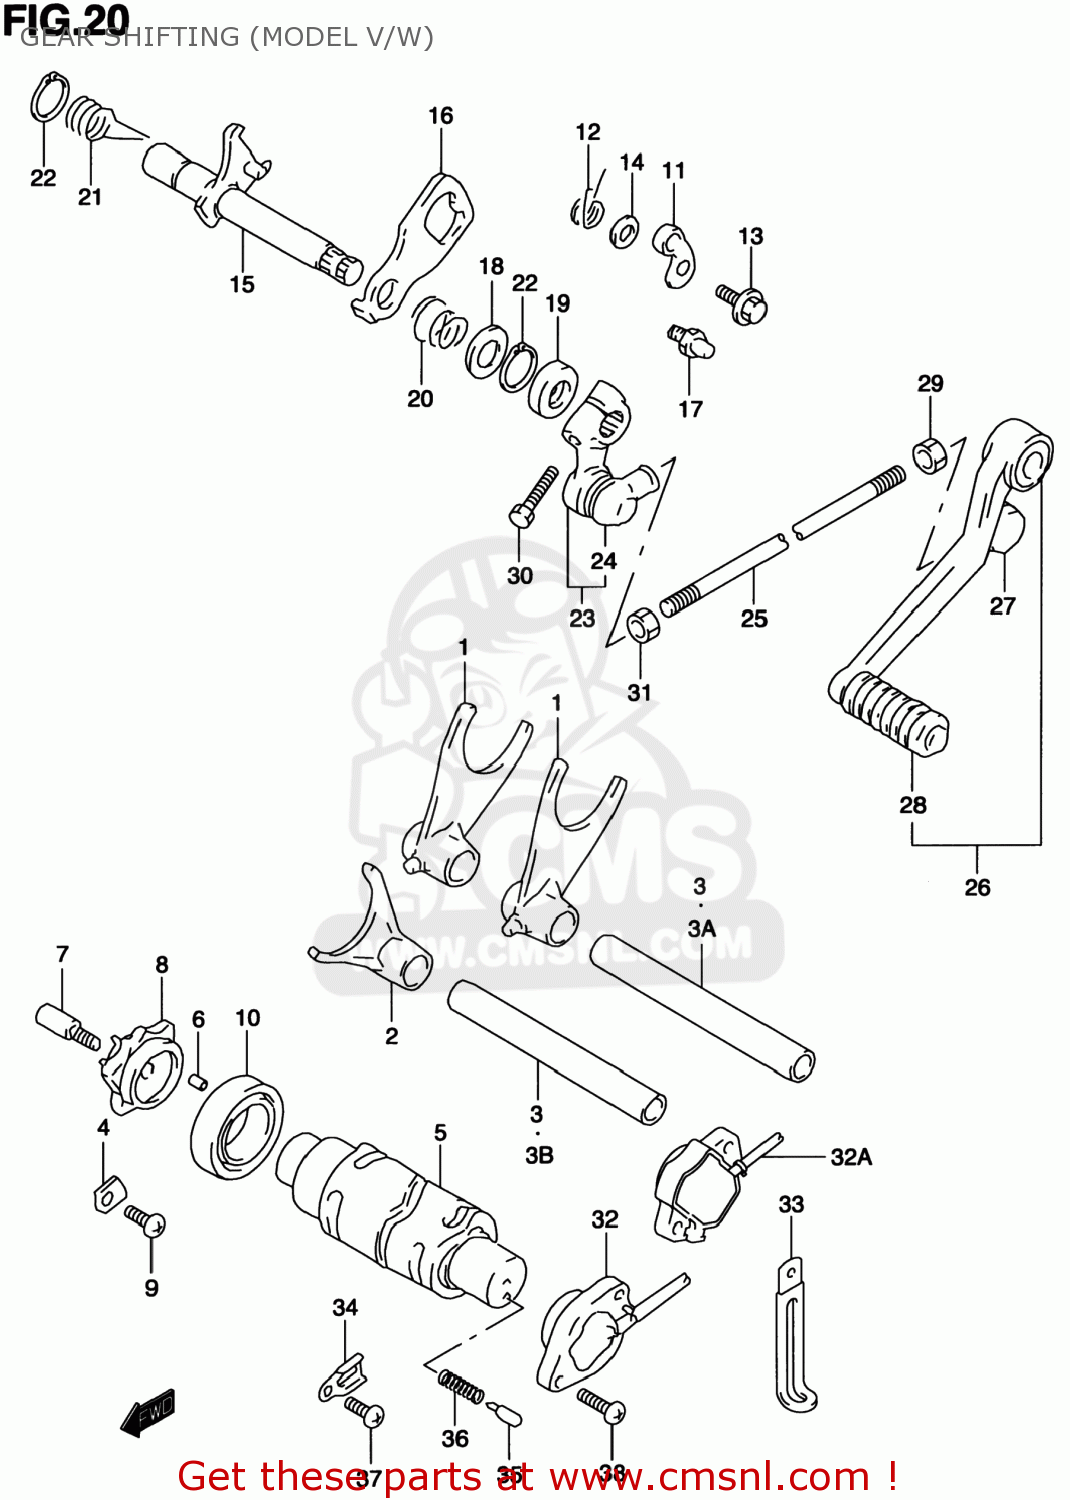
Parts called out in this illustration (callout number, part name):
1	FORK,GEAR SHIFT NO.1
2	FORK,GEAR SHIFT NO.3
3	SHAFT,GEAR SHIFT FORK(L:115)
3A	SHAFT,GEAR SHIFT FORK
3B	SHAFT,GEAR SHIFT FORK NO.2
4	RETAINER
5	CAM,GEAR SHIFT
6	PIN
7	PIN,SHIFT CAM DRIVEN GEAR
8	PLATE,GEAR SHIFT CAM
9	SCREW
10	BEARING
11	STOPPER,GEAR SHIFT CAM
12	SPRING,SHIFT CAM STOPPER
13	BOLT(6X14.3)
14	WASHER
15	SHAFT,GEAR SHIFT
16	PLATE,GEAR SHIFT CAM DRIVE
17	STOPPER,GEAR SHIFT CAM
18	SHIM(14X22X1)
19	SEAL,OIL(14X22X6)
20	SPRING
21	SPRING
22	CIRCLIP
23	ARM,GEAR SHIFT LINK
24	COVER,DUST
25	ROD,GEAR SHIFT LINK
26	LEVER ASSY,GEAR SHIFT
27	COVER,DUST
28	RUBBER,GEAR SHIFT PEDAL
29	NUT
30	BOLT
31	NUT
32	BASE ASSEMBLY,GEAR SHIFT TERMINAL
32A	BASE ASSY,GEAR SHIFT TERMINAL
33	CLAMP(L:45)
34	CLAMP,GENERATOR LEAD WIRE
35	PIN(5X15.5)
36	SPRING
37	SCREW
38	SCREW
